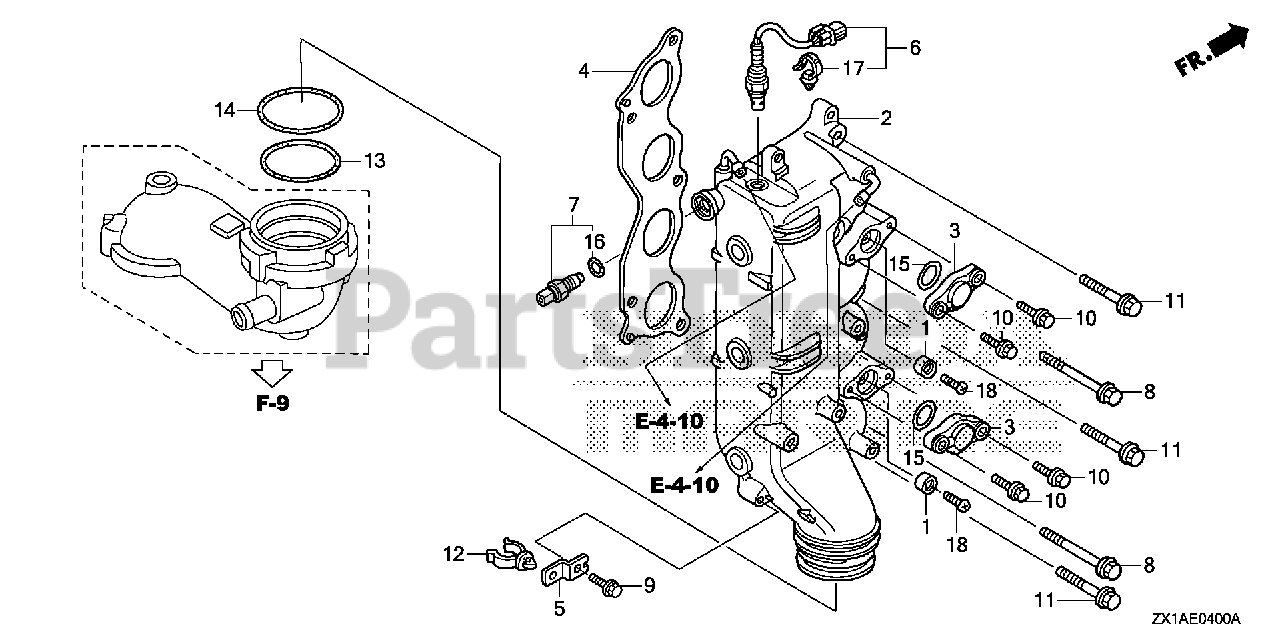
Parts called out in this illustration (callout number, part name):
1	METAL, ANODE
2	KIT,MANIFOLD*NH8*
2	MANIFOLD, EX. *NH8* (DARK GRAY)
3	COVER, EX. MANIFOLD *NH8* (DARK GRAY)
4	GASKET, EX. MANIFOLD
5	BRACKET, WATER TUBE CLAMP
6	SENSOR, LAF
7	SENSOR ASSY., WATER TEMPERATURE
8	BOLT, FLANGE (10X75)
9	BOLT, FLANGE (6X14)
10	BOLT, FLANGE (6X22)
11	BOLT, FLANGE (10X45)
12	CLAMP B, WATER TUBE
13	O-RING (76.4X3.1)
14	O-RING (79.8X3.1)
15	O-RING (37X2.4)
16	O-RING (9.5X1.9)
17	CLIP, HARNESS BAND (145.2MM) (NATURAL)
18	BOLT, FLANGE (6X18)
18	SCREW, PAN (6X18)
